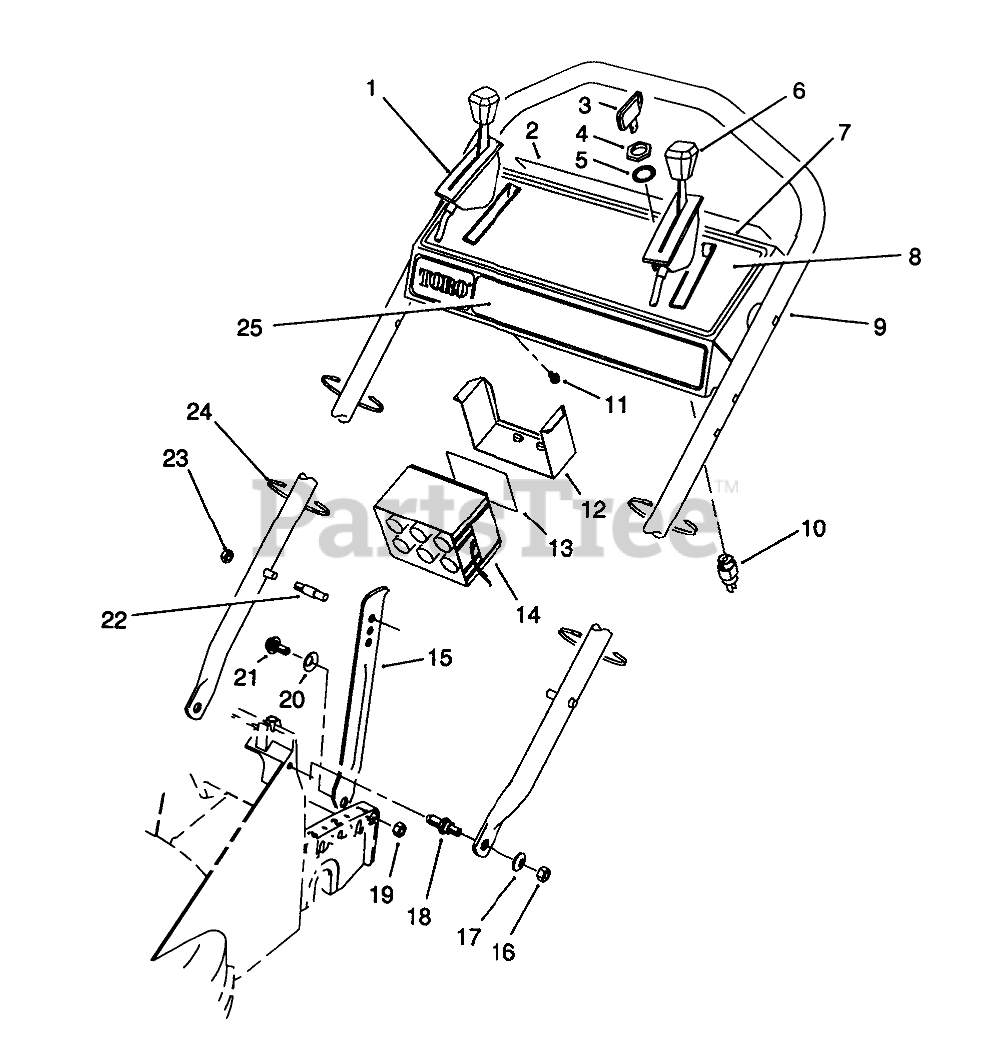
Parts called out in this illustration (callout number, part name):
1	Control-Ground Speed Bend Type #3 Sheath Lg. 51-1/4" Wire Lg. 2-1/8"
2	DECAL-PANEL, DANGER
3	KEY-IGNITION
4	NUT-HH
5	WASHER-TOOTH, INTERNAL
6	ControI-Throttle Bend Type #2 Sheath Lg. 44-3/4" Wire Lg. 2-1/2"
7	Panel-Control
8	DECAL - CONTROL PANEL
9	HANDLE
10	Switch-Starter (Incl. Ref. #4-5)
11	SCREW-HWHTF
12	Retainer-Battery
13	Decal
14	BATTERY ASSEMBLY
15	HANDLE LATCH
16	Nut-Lock
17	WASHER-BELLEVILLE
18	SHOULDER SCREW STUD
19	NUT-LOCK, NI
20	WASHER-BELLEVILLE
21	SHOULDER SCREW LATCH
22	HANDLE PIN
23	NUT-LOCK, NI
24	TIE-CABLE
25	DECAL - KEY LECTRIC
